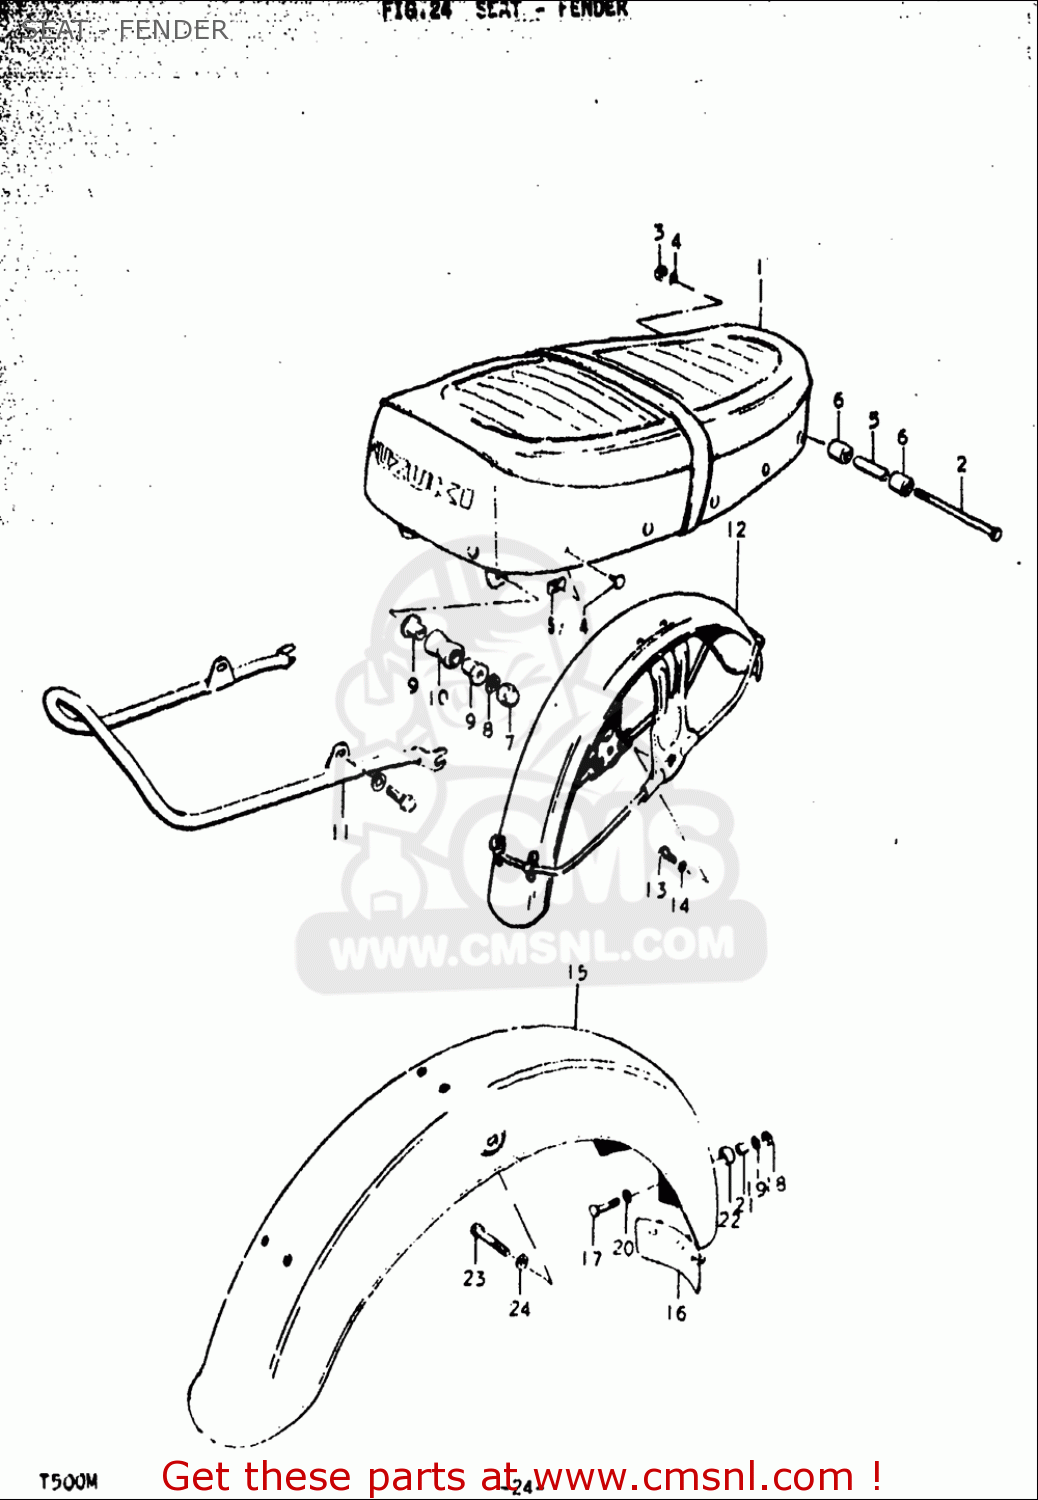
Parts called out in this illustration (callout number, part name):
2	BOLT 8X125
3	NUT
4	WASHER,LOCK
7	NUT
8	WASHER,LOCK
10	BUSH
13	BOLT
14	WASHER,LOCK
16	GUIDE,RR FENDER MUD
17	BOLT
18	NUT
19	WASHER,LOCK
20	WASHER(6.5X24X1.6)
21	SPACER(6.5X10X7)
22	CUSHION
23	BOLT
24	WASHER
